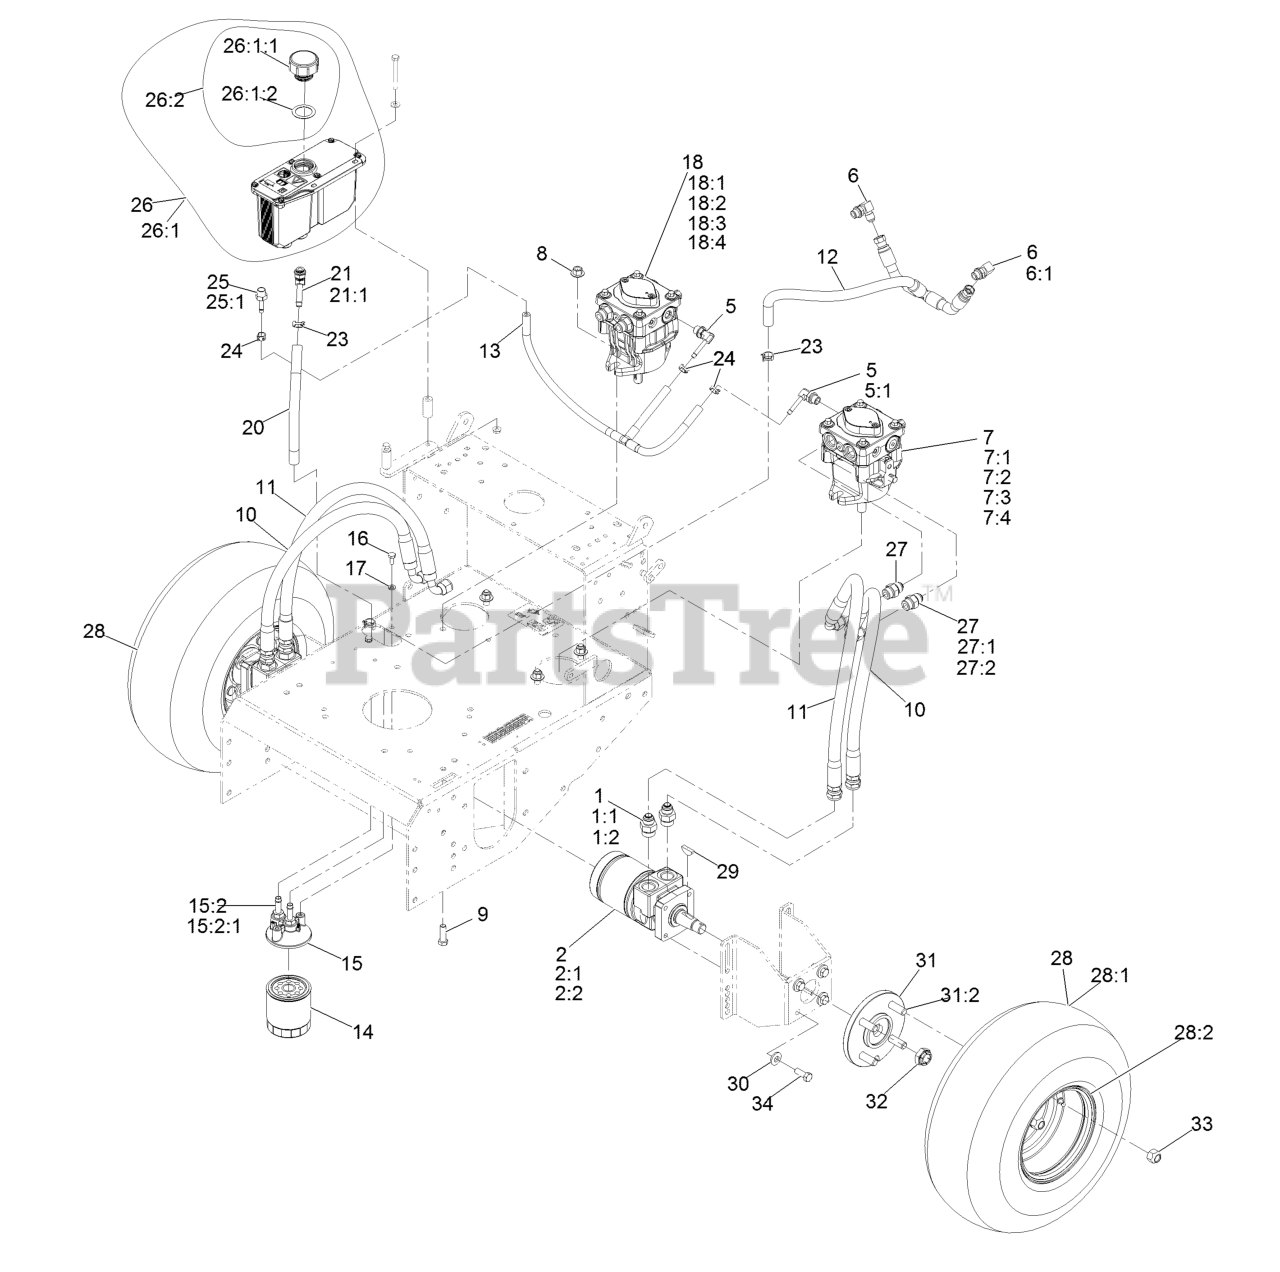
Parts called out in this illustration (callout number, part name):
1	Adapter-Straight
1:1	O-Ring
1:2	O-Ring-37 Flare #8
2	HYD Motor ASM
2:1	Seal Kit
2:2	Bearing And Seal Kit
5	Elbow-90 DEG
5:1	O-Ring
6	Fitting-Elbow, 90 DEG
6:1	O-Ring
7	LH HYD Pump ASM
7:1	Input Shaft Kit
7:2	Bearing-Thrust
7:3	Cylinder Block Kit
7:4	Seal Overhaul Kit
8	Nut-Whizlock 3/8-16
9	Screw-HH 3/8-16 X 1 1/4
10	HYD Hose ASM
11	HYD Hose ASM
12	Charge Hose ASM
13	Case Drain Hose ASM
14	Element, Oil Filter (Winter)
14	Element, Oil Filter
15	Filter Head ASM
15:2	Adapter-Straight
15:2:1	O-Ring
16	Screw-HH 1/4-20 X 5/8
17	Washer-Lock 1/4 Heavy
18	RH HYD Pump ASM
18:1	Input Shaft Kit
18:2	Bearing-Thrust
18:3	Cylinder Block Kit
18:4	Seal Overhaul Kit
20	Hose-Charge
21	Fitting-Barbed, 45 DEG
21:1	O-Ring
23	Clamp-Hose 11/16
24	Clamp-Hose 17/32
25	Adapter-Straight
25:1	O-Ring
26	ASM, HYD Reservoir
26:1	Reservoir-HYD
26:1:1	Cap-Reservoir, HYD
26:1:2	Gasket-Cap
26:2	Decal-Warning
27	Adapter-Straight
27:1	O-Ring-SAE #8
27:2	O-Ring-37 Flare #8
28	Wheel And Tire ASM
28:1	Tire-Turfmaster
28:2	Rim-Wheel
29	Key-Woodruff 1 X 1/4
30	Washer-Spring Disc 3/8
31	Wheel Hub ASM
31:2	Stud-Wheel
32	Nut-Lock
33	Nut-Lug 1/2-20
34	Screw-HH 3/8-16 X 1
